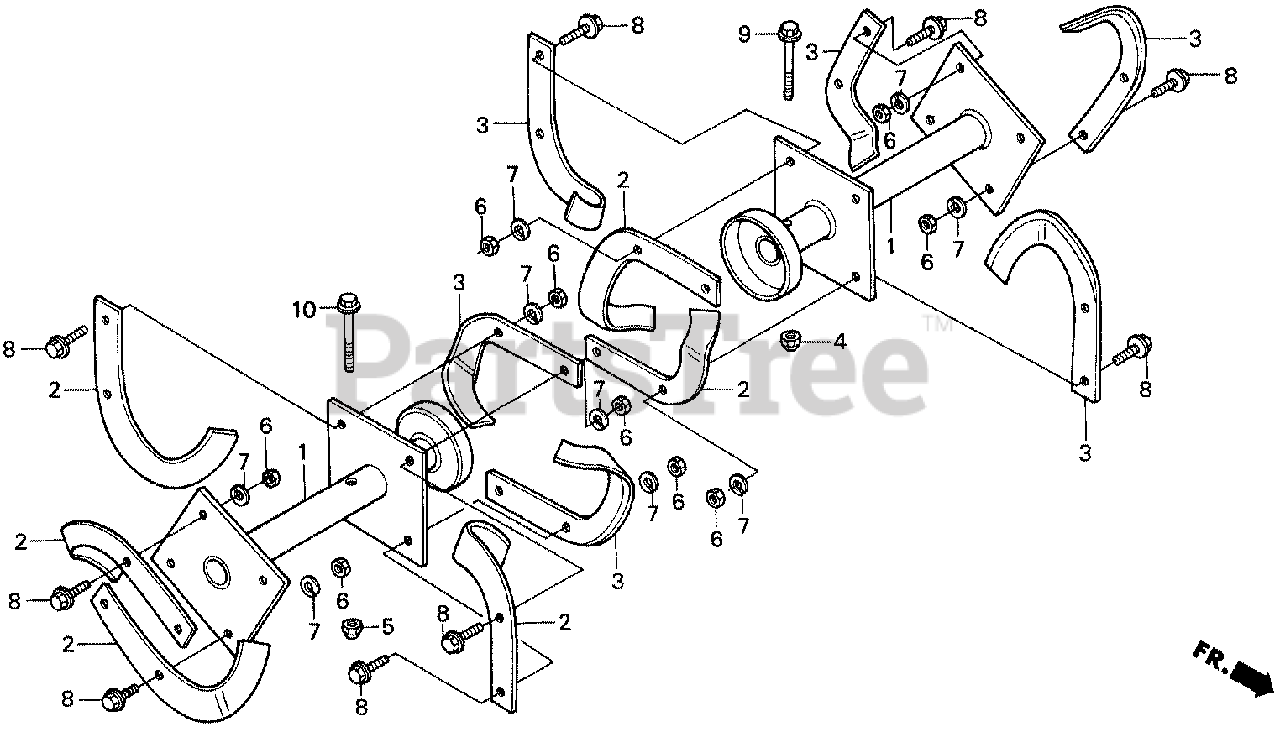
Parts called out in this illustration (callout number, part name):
1	SHAFT, ROTARY PIPE (NOT AVAILABLE)
1	SHAFT, ROTARY PIPE
2	TINE A, ROTARY
3	TINE B, ROTARY
4	NUT, SELF-LOCK (8MM)
4	NUT, SELF-LOCK (10MM)
5	NUT, SELF-LOCK (10MM)
6	NUT, HEX. (10MM)
6	NUT, FLANGE (10MM)
7	WASHER, SPRING (8MM)
8	BOLT, FLANGE (10X25)
9	BOLT, FLANGE (10X50)
9	BOLT, FLANGE (8X50)
10	BOLT, FLANGE (10X50)
